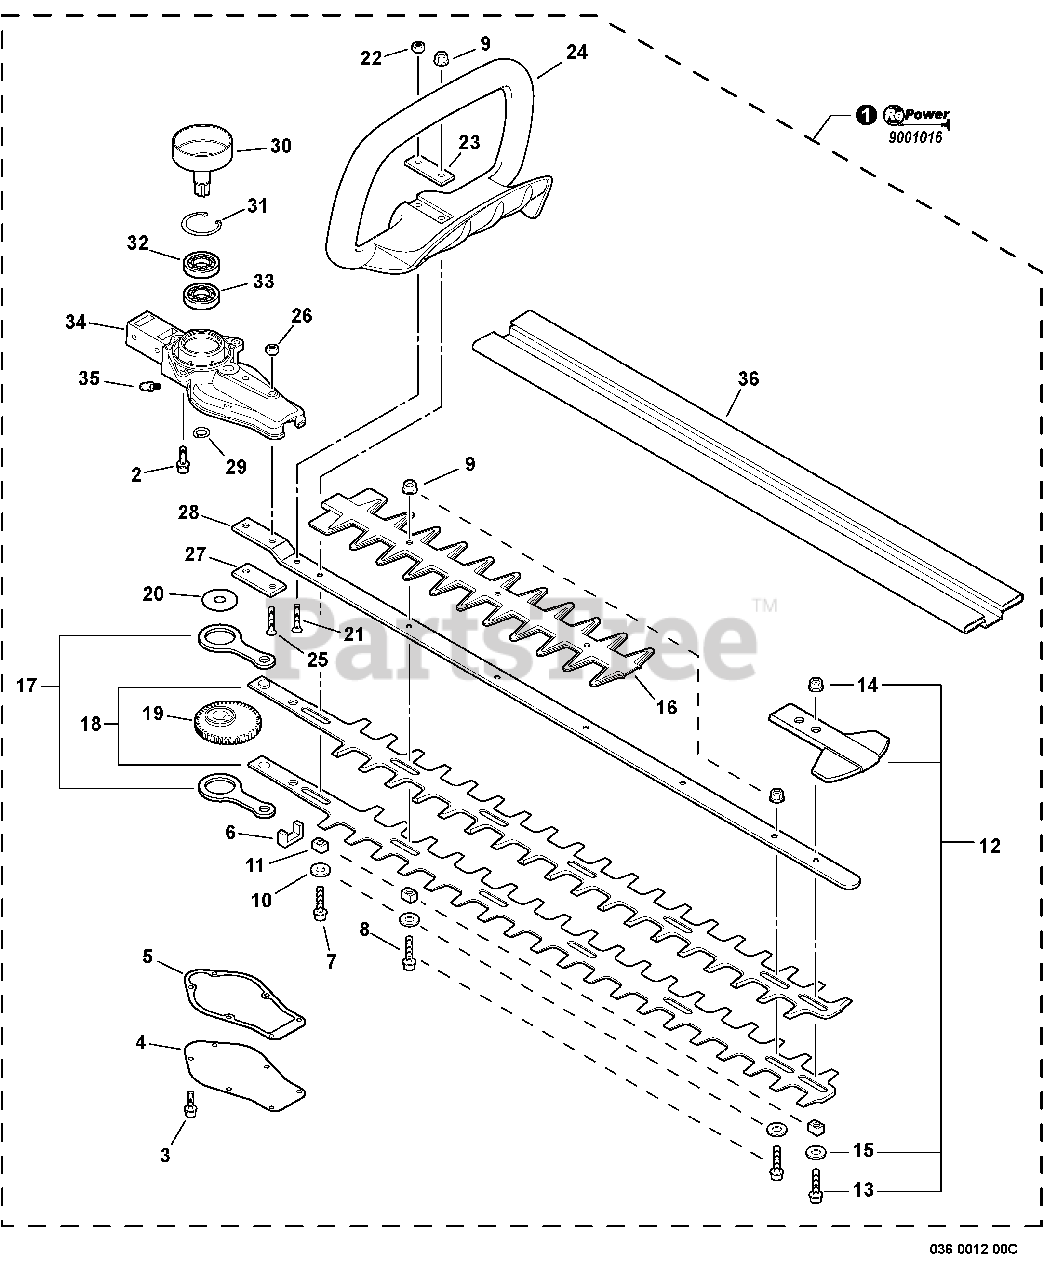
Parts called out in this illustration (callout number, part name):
1	RePower GEAR CASE/BLADES KIT
2	SCREW - 5X20
3	SCREW - 4X10
4	LID, GEAR CASE
5	GASKET, GEAR CASE
6	SEAL, FELT
7	SCREW - 5X40
8	SCREW - 5X20
9	LOCKNUT - 5
10	GUIDE, BLADE
11	WASHER - 6
12	TIP GUARD KIT
13	SCREW - 5X20
14	LOCKNUT - 5
15	WASHER - 6
16	SHIELD, BLADE
17	ROD, CONNECTING
18	BLADE - 24" (60cm)
19	GEAR - DRIVE
21	SCREW - 5X30
22	LOCKNUT - 5
24	HANDLE - FRONT
25	SCREW - 6X25
26	LOCKNUT - 6
28	SUPPORT, BLADE
29	RING, RETAINING - 14
30	DRUM, CLUTCH
31	RING, RETAINING - 35
32	BEARING, BALL - 6202
33	BEARING, BALL - 6202
34	CASE, GEAR
35	FITTING, GREASE
36	COVER, BLADE - 24" (60cm)
